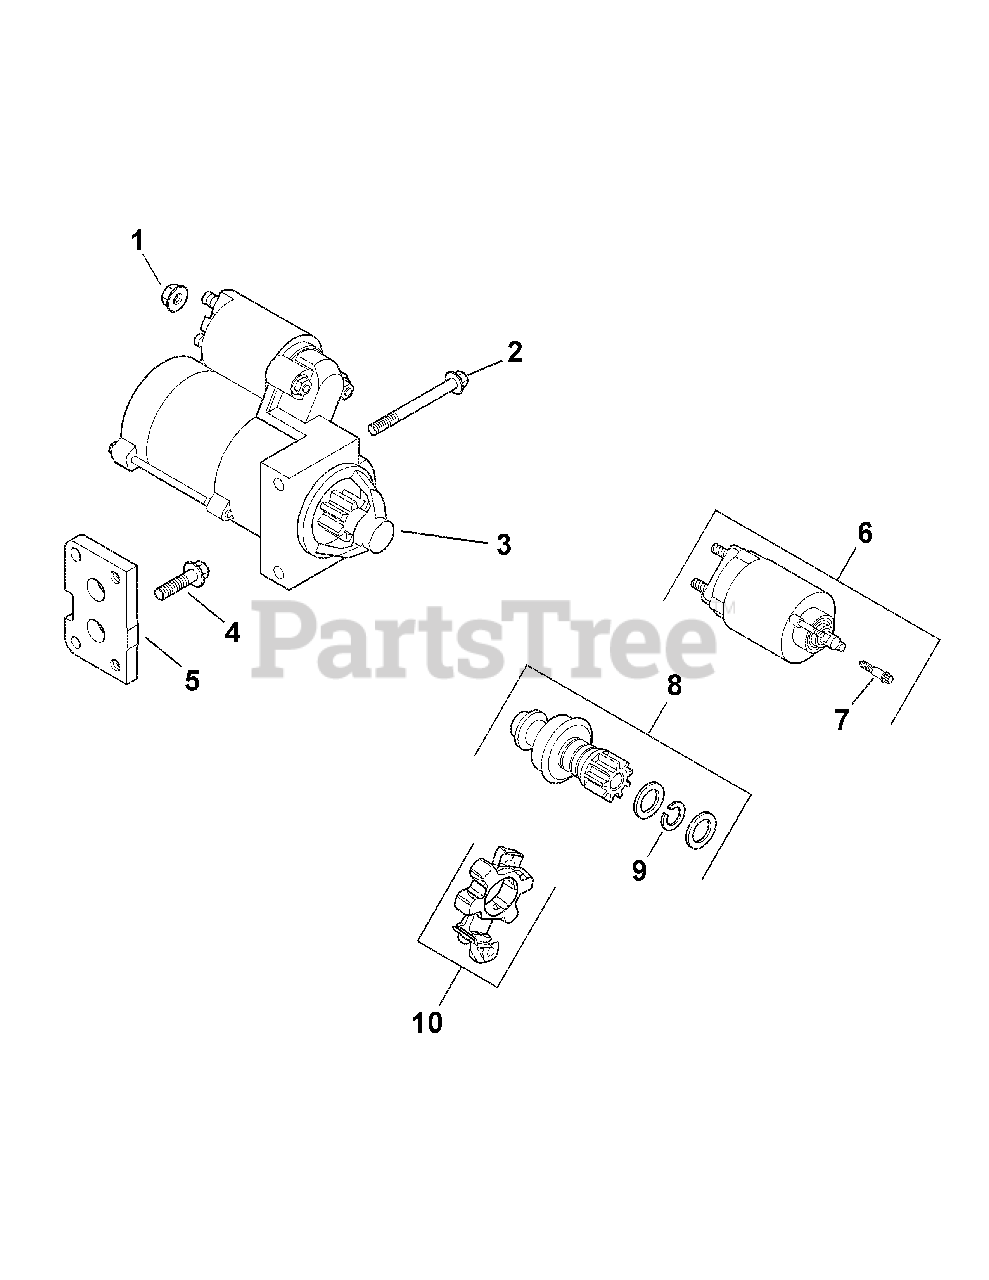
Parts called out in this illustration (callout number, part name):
1	Nut, Flg, M8 x 1.25
2	Screw, Flg, M8 x 1.25 x 80
3	Starter Ass’y, Solenoid Shift (Includes 6-10)
4	Screw, Flg, M8 x 1.25 x 30
5	Plate, Starter
6	Kit, Solenoid (Includes 7)
7	Screw, External Torx Head
8	Kit, Starter Pinion (Includes 9)
10	Brush, Holder
